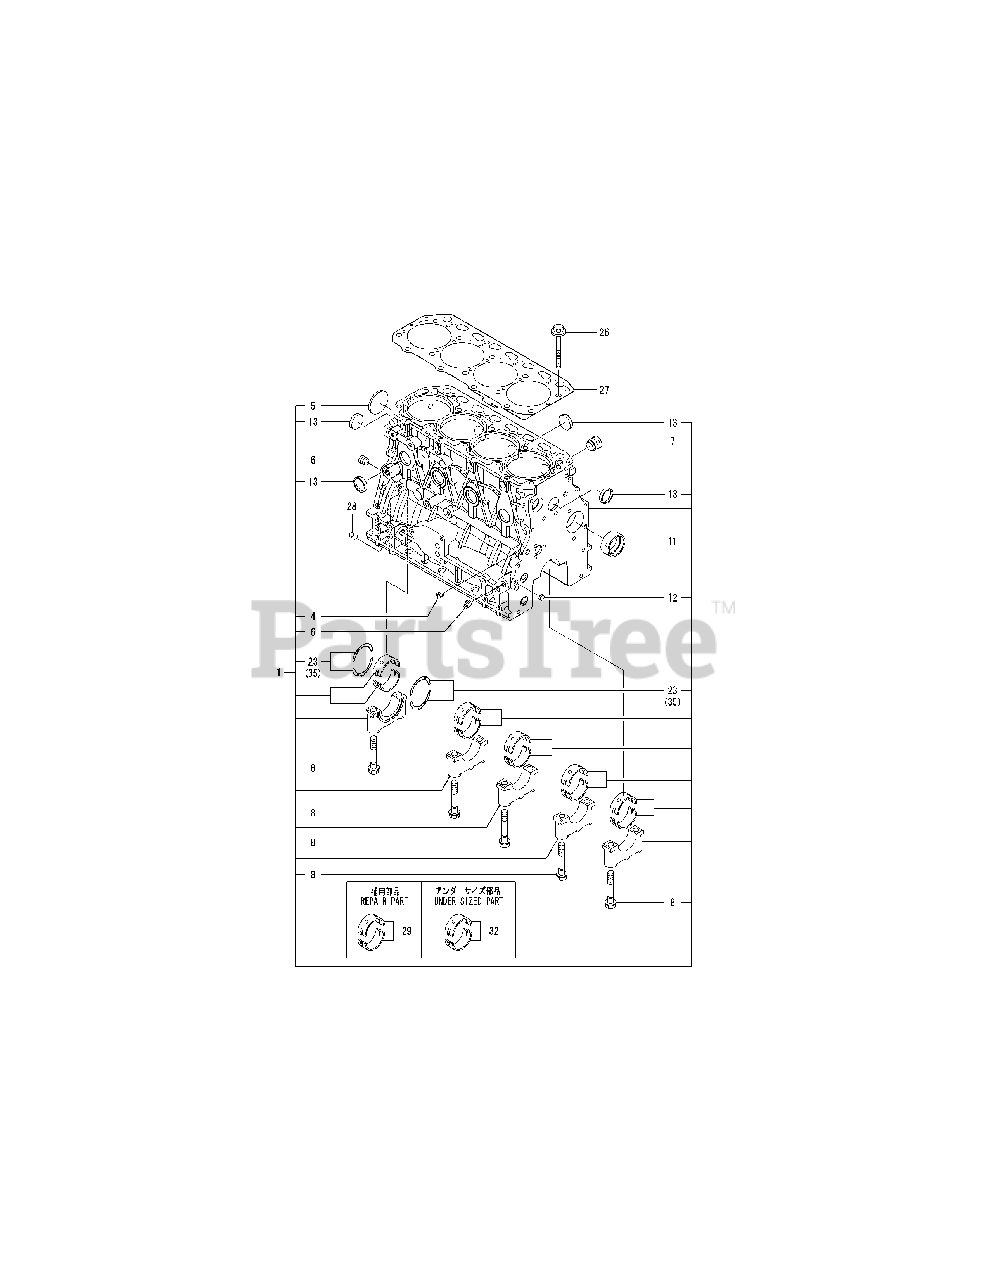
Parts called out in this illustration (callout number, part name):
1	BLOCK ASSY, CYLINDER
8	BOLT, METAL CAP
11	BUSH, CAMSHAFT A
23	METAL ASSY, THRUST
26	BOLT, CYLINDER HEAD
27	GASKET, CYL.HEAD
29	MAIN BEARING SET
32	MAIN METAL US=0.25
35	BEARING, THRUST.25OS
